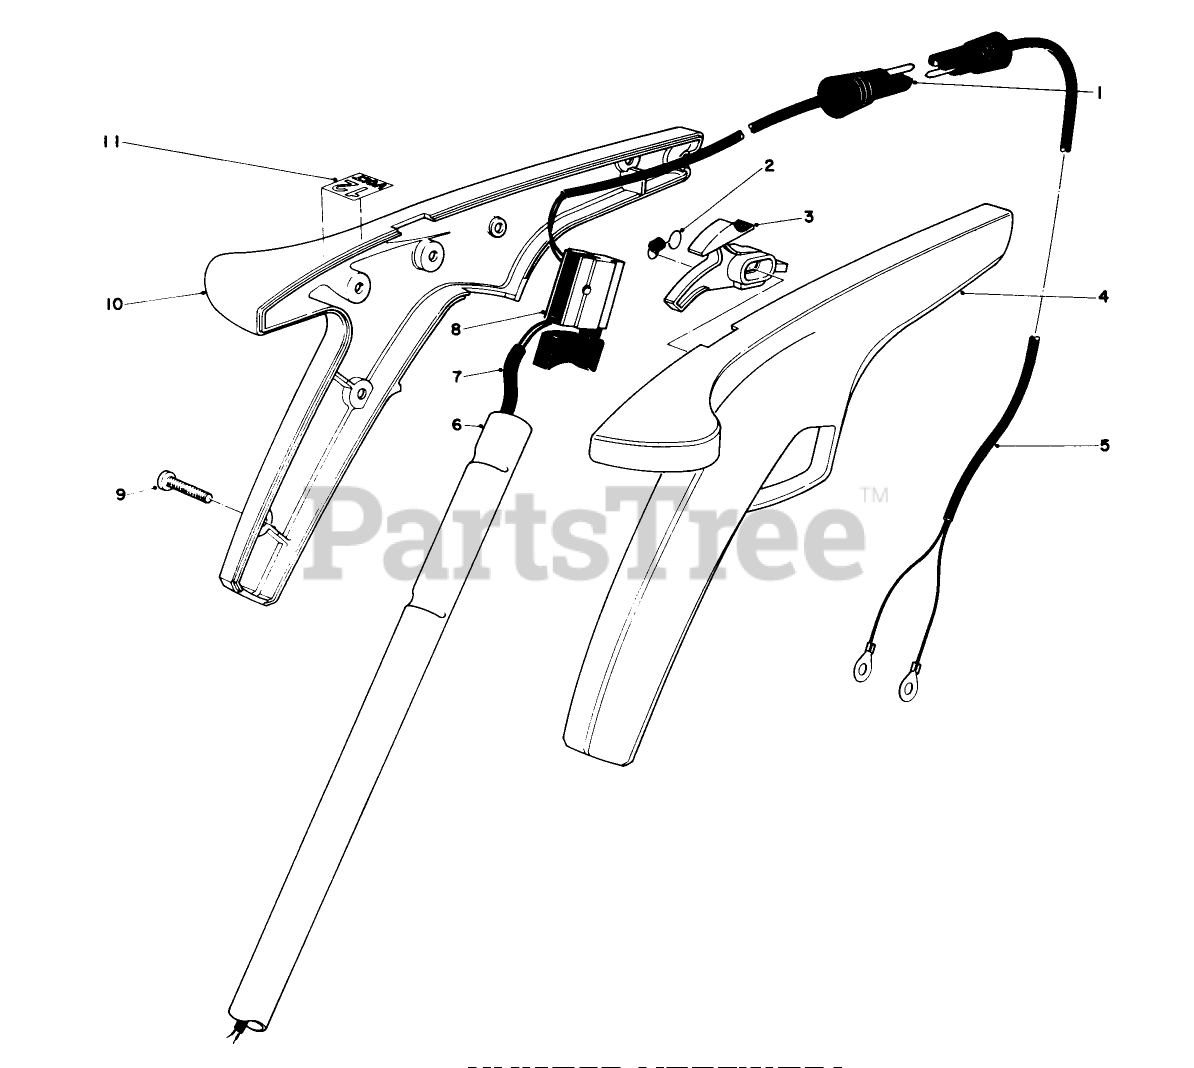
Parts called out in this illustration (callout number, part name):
1	Wire Harness, Unit
2	Spring
3	Safety Trigger Stop
4	Hand Grip L.H.
5	Wire Harness, Battery
7	Wiring Harness
8	SWITCH SINGLE SPEED
9	Screw
10	41 Hand Grip R.H.
11	Decal-12 Volt
